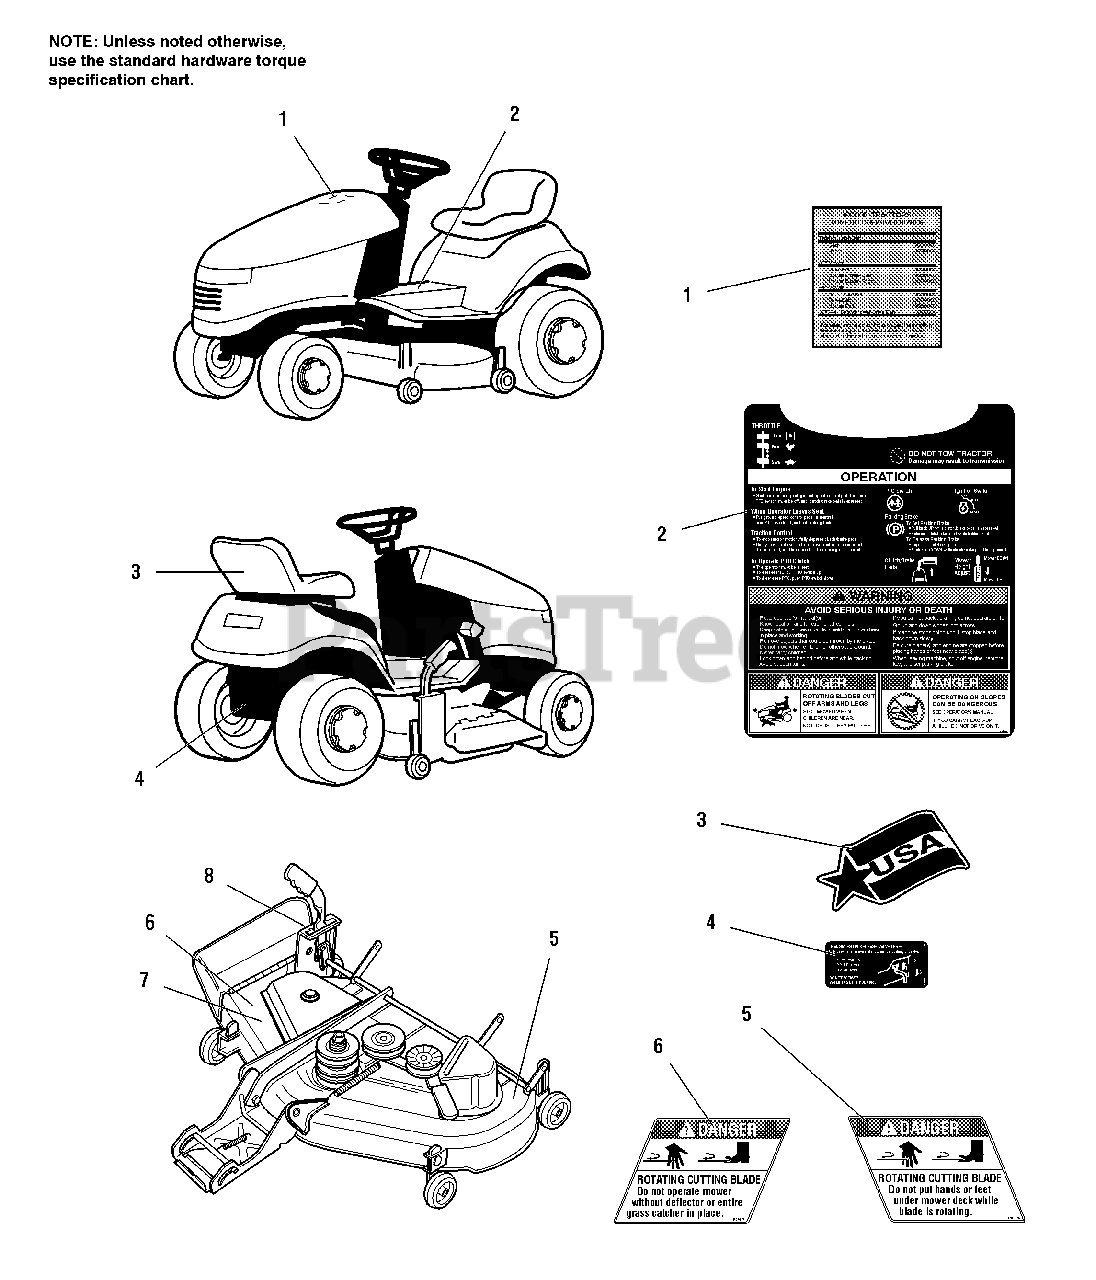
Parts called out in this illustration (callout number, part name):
1	DECAL, Belt/Blade
2	DECAL, Operating Instructions
3	DECAL, Logo, USA
4	DECAL, Release Valve
5	DECAL, Danger, Rotating Cutting Blade
6	DECAL, Danger, Chute in Place
7	DECAL, Cutting Width, 38"
7	DECAL, Cutting Width, 44"
8	DECAL, Height of Cut
